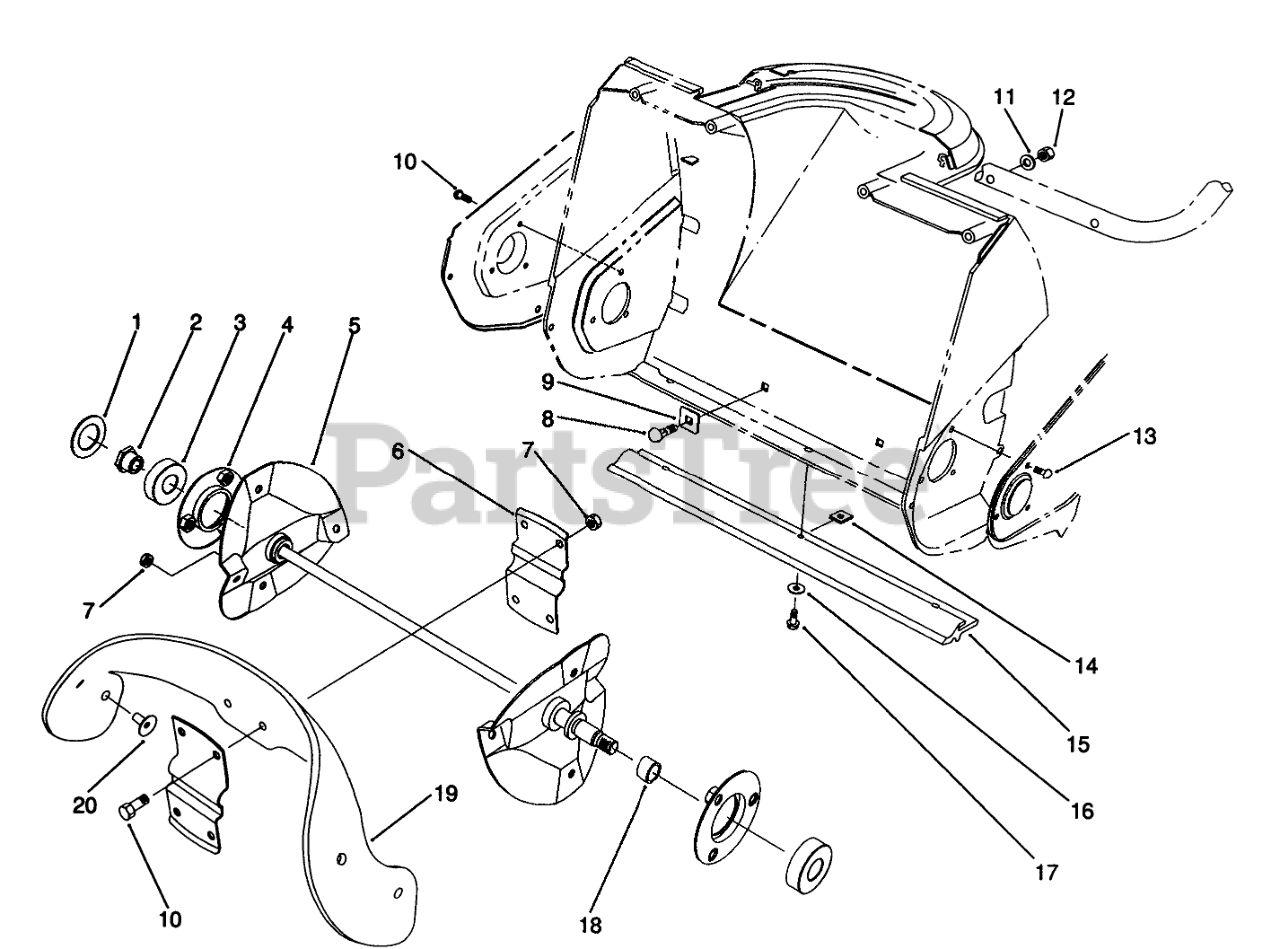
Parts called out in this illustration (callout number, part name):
1	WASHER-RUBBER
3	BEARING-BALL
4	FLANGE BEARING ASM
5	Rotor
6	Support-Rotor
7	NUT-LOCK, NI
8	SCREW-CARR
9	WASHER-SQUARE
10	SCREW-HHF
11	WASHER
12	NUT-LOCK, NI
13	SCREW-HH
14	"U" TYPE SPEED NUT
15	SCRAPER
16	WASHER-FLAT
17	SCREW-HWHTF
18	SPACER
19	Blade-Rotor
20	SCREW
